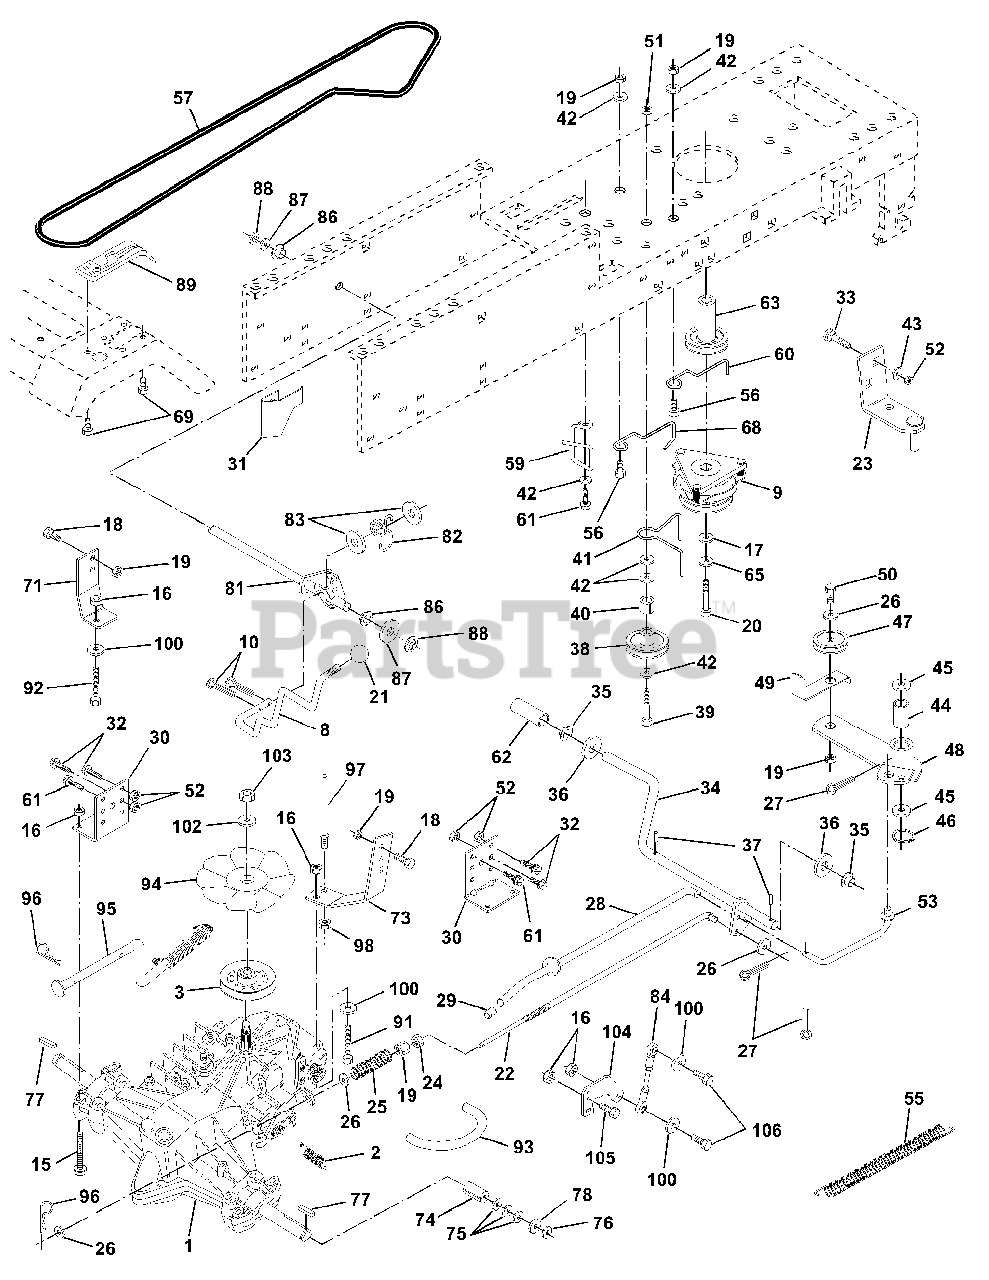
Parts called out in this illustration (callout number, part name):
1	Transaxle w/cas Hydro 310-0650
2	Spring, Return, Brake
3	Pulley, Transaxle Hydro 750 LT
8	Rod Shift Hydro LT
9	Clutch Elecric
10	Pin Cotter 1/8 x 1 CAD
15	Bolt Hex 5/16-18 Unc Flghd
16	Nut Lock Hex W/Ins. 5/16-18 Unc P
17	Washer 1-1/2 OD x 15/32 ID x .250
18	Bolt Fin Hex 3/8-16 Unc x 1 Gr.5
19	Nut Lock Hex W/Ins 3/8-16 Unc
20	Bolt, Hex 7/16-20 x 4-1/4 Ga. 5
21	Knob Deluxe 1/2-13 UNC BLK/BLK
22	Rod, Brake Hydro
23	Bracket Asm Mtg CL
24	Nut Hex Jam 3/8-16 UNC
25	Spring, Brake Rod
26	Washer
27	Pin Cotter 1/8 x 3/4 CAD.
28	Rod, Parking Brake
29	Cap, Parking Brake
30	Bracket, Transaxle
31	Keeper Belt Lh
32	Bolt Hex Hd 5/16-18 Unc x 3/4
33	Bolt Carriage 5/16-18 UNC x 3/4
34	Shaft, Foot Pedal 20.500
35	Bearing, Nylon
37	Pin, Roll
38	Pulley, Idler, Flat
40	Spacer Split
41	Keeper, Belt Retainer
42	Washer 13/32 x 13/16 x 12 Ga
43	Washer 11/32 x 5/8 x 12 Ga.
44	Bearing, Nylon
45	Washer, Hardened
46	Ring, Klip
47	Pulley, Idler, V-Groove Plastic
48	Bellcrank Assembly
49	Retainer, Belt Style Spring
50	Bolt
52	Nut Crown Lock 5/16-18
53	Link, Clutch
55	Spring, Return, Clutch
56	Bolt, Fin Hex 3/8-16 UNC x 1 1/4
57	V-Belt, Ground Drive
59	Keeper, Center Span
60	Keeper Belt Engine
61	Screw Thdrol. 3/8-16 x 3/4 Ty. TT
62	Cover, Pedal Premium
63	Pulley, Engine
65	Washer Lock Hvy HLCL Spr 7/16
68	Keeper Belt Engine
71	Strap Torque Lh Hydro 18/20" T
73	Strap Torque Rh Hydro 18/20" T
74	Spacer, Split
75	Washer 25/32 x 1-1/4 x 16 Ga.
77	Key, Square
78	Washer 25/32 x 1-5/8 x 16 Ga
81	Shaft Asm. Cross Hydro 20" Tires
82	Spring Torsion T/A
83	Washer 17/32 x 3/4 x 16 Ga.
84	Rod, Tie Hydro 20" Tires SPH Ball 4.75
86	Bushing Rod Strig. 629/632 ID
87	Washer 21/32 x 1-1/4 x 16 Ga.
88	Ring Klip #5304-62
89	Console, Hydro YT/GT Fender
91	Bolt Fin Hex 5/16-18 x 2-1/4
92	Bolt Fin Hex 5/16-18 Unc x 1-1/2
93	Line Fuel Hydro 4"
94	Fan, Hydro 7"
95	Control Asm. Bypass Hydro
96	Retainer Spring 1" Zinc/Cad
97	Keeper Belt Rh Hydro 0750.18/20"
98	Nut Keps Hex 3/8-16 Unc
100	Washer 11/32 x 3/4 x 16 Ga.
102	Washer Belleville .501D x 1.50D
103	Nut Hex Jam Toplock 1/4-20 Unf
104	Arm, Control Hydro
105	Screw Cap Hex 5/16 x 18 x 1
106	Bolt Fin Hex 5/16-18 Unc x 1-1/4
